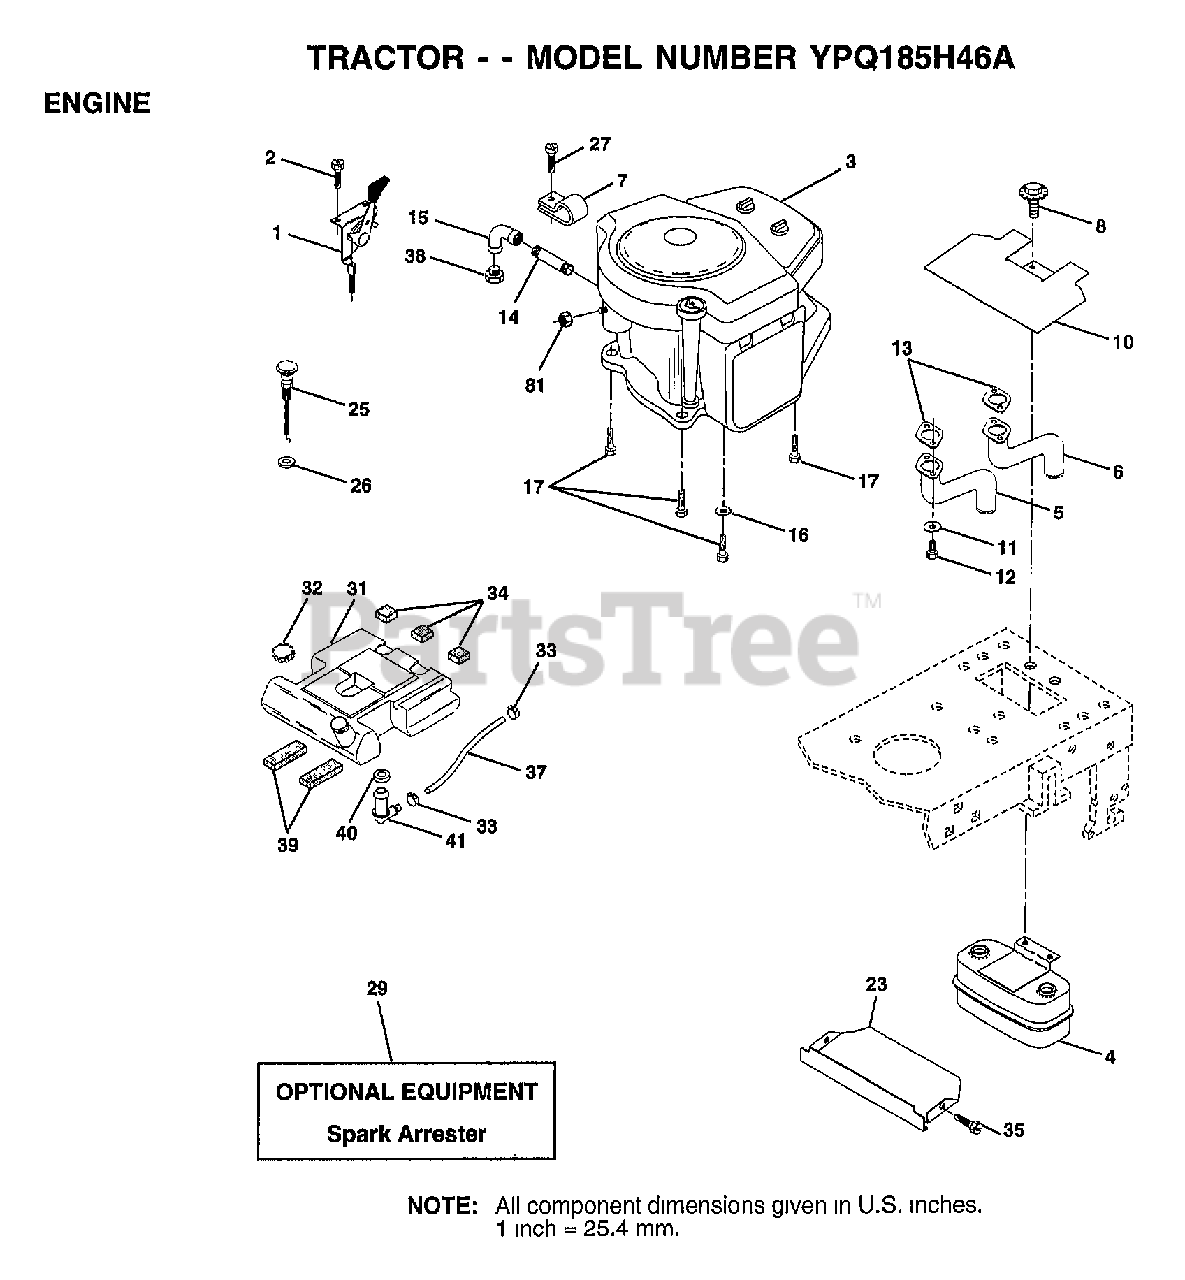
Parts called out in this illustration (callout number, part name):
1	CONTROL THRT 35.5
2	SCREW LT
4	MUFFLER.TW.LOTONE
5	EXHAUST.B&S.18.LH
6	EXHAUST.B&S.18.RH
7	CLAMP.TUBE.DBL.EN
8	BOLT.5/16-18.UNC
10	SHIELD.HEAT.
11	LOCKWASHER
13	GASKET MUFFLER
14	PIPE NIPPLE LT
15	ELBOW
16	LOCKWASHER
17	SCREW LT
23	SHIELD.BRN/DBR.GD
25	CONTROL.CHOKE.37
26	"NUT,KEPS 3/8-24IM"
27	"SCREW-TT,10-32 FL"
31	TANK FUEL REAR
32	CAP ASM FUEL
33	HOSE CLAMP
34	PAD-SPACER LT
35	SCREW
37	FUEL LINE T
39	PAD IDLER TI
40	BUSHING OUTLET T
41	STEM.TANK.FUEL
81	NUT
